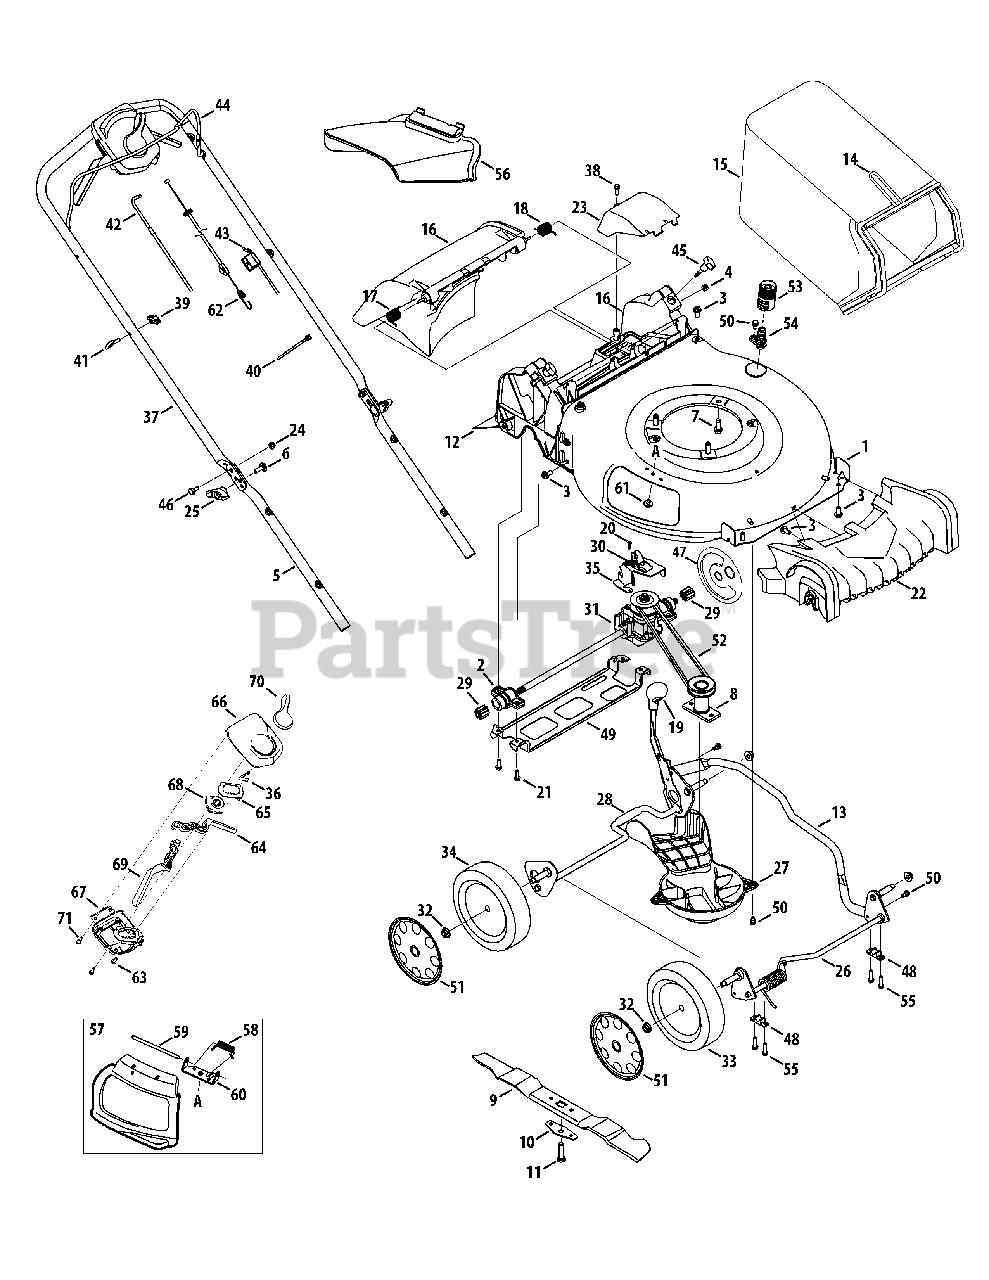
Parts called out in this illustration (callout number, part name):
2	Bearing Assembly
3	Screw, 5/16-14 x .750
4	Nut, Sq., 1/4-20
5	Lower Handle
6	Carriage Screw ,5/16-18
7	Screw, 3/8-16 x 1.00
8	Blade Adapter
9	Mulching Blade
10	Blade Bell Support
11	Screw, 3/8-24 x 1.50
12	Trailing Shield
14	Grass Catcher Frame
16	Rear Discharge Door Assembly
17	Torsion Spring - RH
18	Torsion Spring - LH
19	Adjustment Lever Knob
20	Screw, Hex Washer, .159 x .43
21	Screw, 1/4-15 x 1.25
22	Front Cover
23	Transmission Cover
24	Nut, Flange Lock, 1/4-20
26	Front Axle Assembly
27	Engine Baffle
28	Rear Axle Assembly
29	Spur Gear, 10T
30	Exten. Spring, 2.405
31	Transmission Assembly
32	Flange Lock Nut, 3/8-16
33	Front Wheel
34	Rear Wheel
35	Transmission Bracket
38	Screw, 1/4-15 x .750
40	Cable Tie
41	Rope Guide
42	Speed Adjustment Cable
43	Control Cable
45	Wing Nut
46	Sldr. Screw, .375 x .126 x 1/4-20
47	Wheel Dust Cover
48	Bushing, Lock, .505 Dia. X .62
49	Rear Support Bracket
50	Scr., Shldr., 1/4-20 x .50
51	Hubcap, 8"
53	Water Nozzle Adapter
54	Water Nozzle
55	Screw, 1/4-15 x 1.000
56	Side Discharge Chute
57	Mulch Plug (Incl. 58-60)
58	Torsion Spring
60	Chute Deflector Bracket
61	Screw, 1/4-20 x .500
62	Drive Cable
63	Screw, 1/4-15 x .750
64	Control Lever LH
65	Cable Adjust Plate
66	Upper Housing
67	Lower Housing
68	Speed Adjust Actuator
69	Control Lever RH
70	Speed Select Lever
71	Screw, Shldr, 1/4-15 x .970
